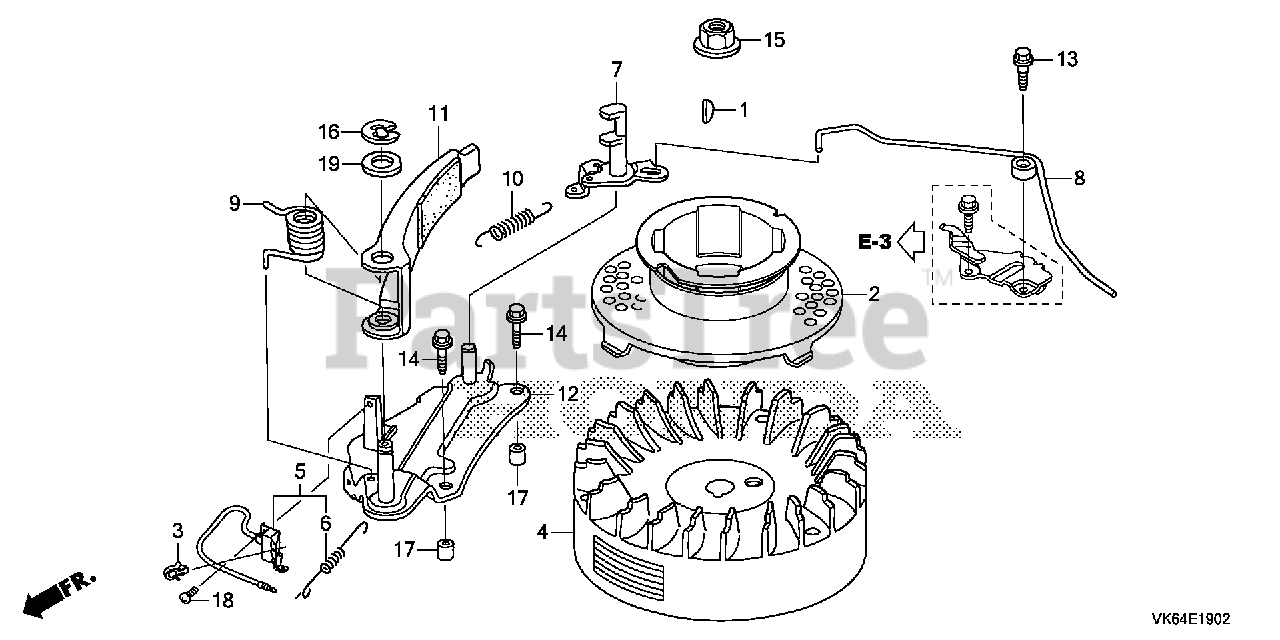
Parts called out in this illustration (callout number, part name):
1	KEY, SPECIAL WOODRUFF (25X18)
2	PULLEY, STARTER
3	CLIP, IGNITION WIRE (8MM)
4	FLYWHEEL (BRAKE)
5	SWITCH ASSY., ENGINE STOP (BRAKE)
6	SPRING, SWITCH CONTROL
7	CAM, BRAKE
8	ROD, THROTTLE RETURN
9	SPRING, BRAKE
10	SPRING, BRAKE RETURN
11	BRAKE
12	BASE, BRAKE
13	BOLT, FLANGE (6MM)
14	BOLT, FLANGE (6X23)
15	NUT, SPECIAL (14MM)
16	E-RING (10MM)
17	PIN, DOWEL (8X9)
18	SCREW, PAN (4X8)
19	WASHER, PLAIN (12MM)
